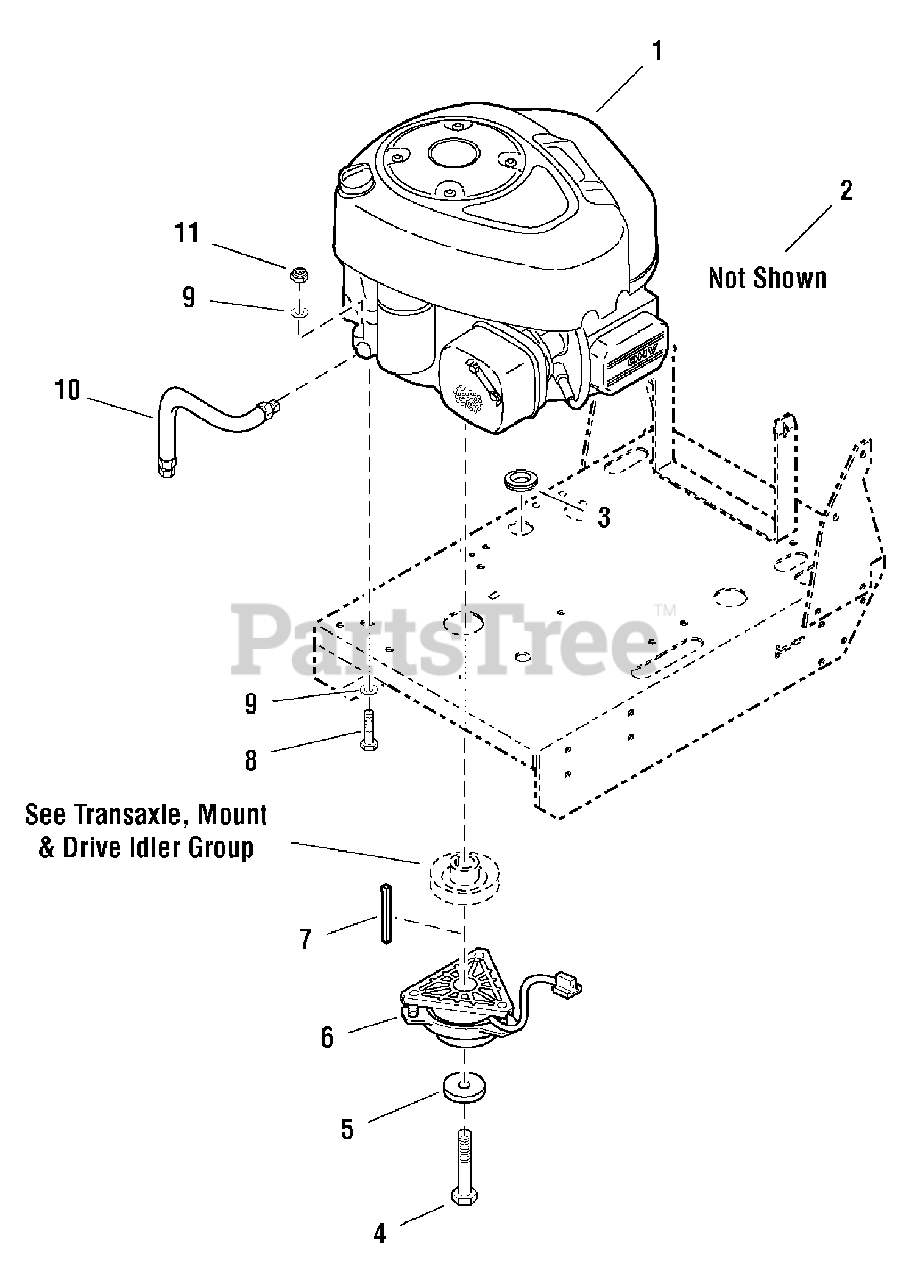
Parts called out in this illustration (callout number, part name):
4	CRANKSHAFT BOLT, 7/16 x 2-3/4
5	CLUTCH RETAINER
6	ELECTRIC CLUTCH
7	KEY, 1/4 Sq. x 2
8	CAPSCREW, Hex Head, 5/16-18 x 2-1/2
9	WASHER, 5/16
10	OIL DRAIN HOSE
11	NUT, Hex Nylon Lock, 5/16-18
